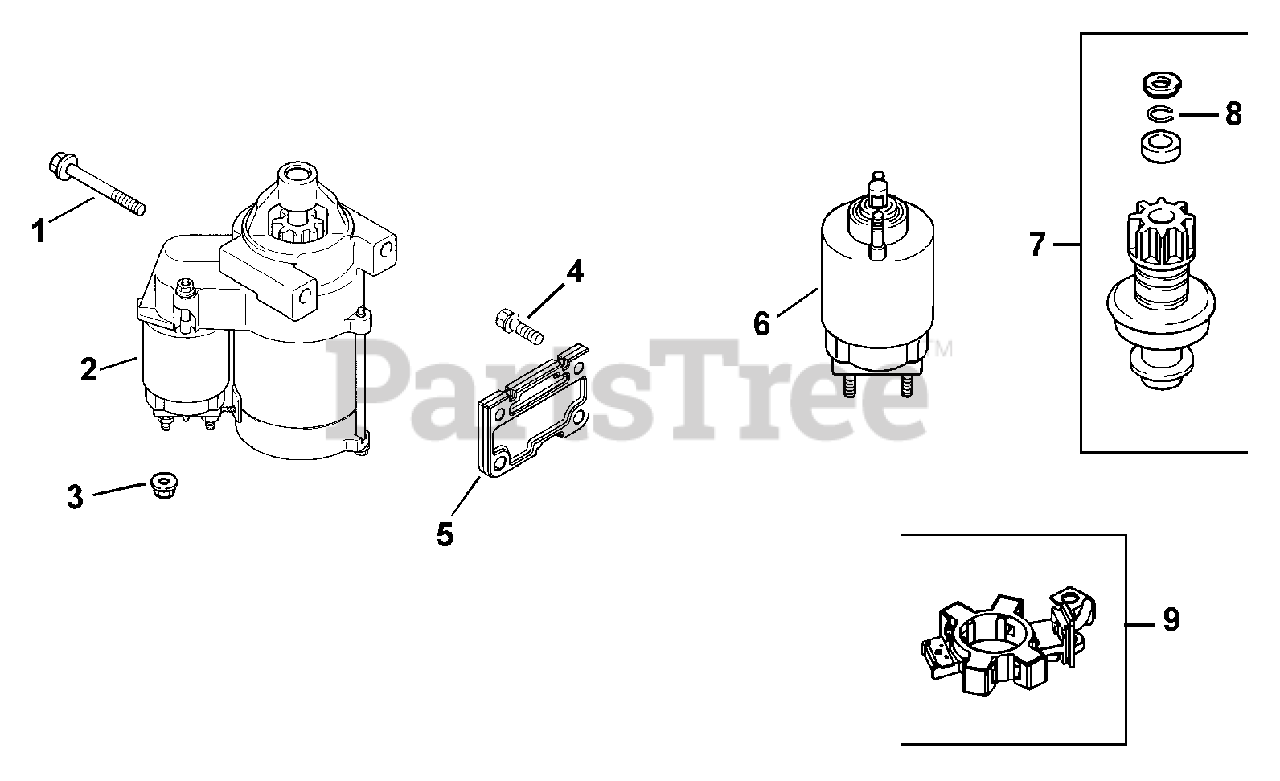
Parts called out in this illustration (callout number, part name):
1	SCREW - USE M-851080-S
2	STARTER, SOLENOID SHIFT-USE 25 098 11-S
4	SCREW, FLG M8X1.25X30
5	PLATE, STARTER - USE 66 146 54-S
7	KIT, STARTER PINION
8	RING, RETAINING
9	KIT, BRUSH HOLDER
